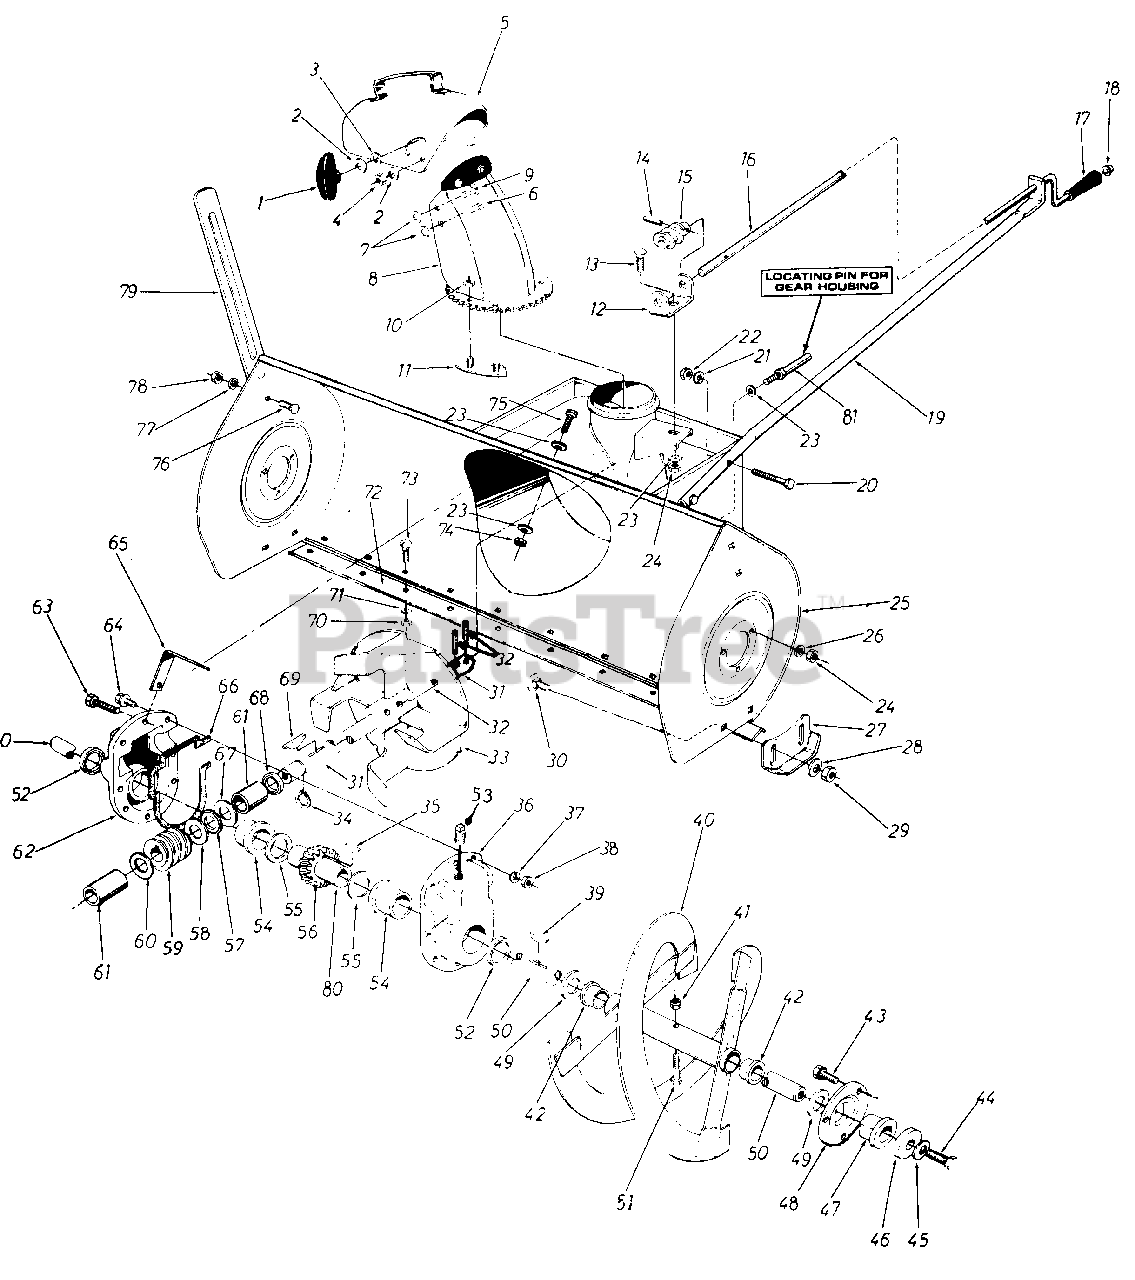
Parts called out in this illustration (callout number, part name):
1	Hand Knob Ass'y.
2	Bell. Wash. .345 I.D. x .88 O.D. x .060
3	Fl.-Wash. .312 I.D. x 1.125 O.D. x .125
4	Hex Cent. L-Nut 5/16-18 Thd.
5	Top Chute Ass'y.
6	Carriage Bolt 5/16-18 x 1.50" Lg.
7	Fl.-Wash. .53 I.D. x 1.25 O.D. x .100
8	Chute Ass'y.
9	Carriage Bolt 5/16-18 x 1.00" Lg.
10	Hex Cent. L-Nut 1/4-20 Thd.
11	Chute Flange Keeper Ass'y.
12	Chute Bracket
13	Carriage Bolt 5/16-18 x .62" Lg.
14	Spring Pin Roll 1/8" Dia. x 1.75 Lg.
15	Worm-R.H. w hree Threads
16	Chute Crank
17	Knob Black 3/8" Dia. Hole
18	Push Nut 3/8" rod.
19	Chute Crank Support Tubing
20	Hex Scr. 3/8-24 x 1.25" Lg.
21	L.-Wash. 3/8" Scr.
22	Hex Ins. Jam L.-Nut 3/8-24 Thd.
23	Bell.-Wash. .345 I.D. x .88 O.D. x .060
24	Hex Nut 5/16-18 Thd.
25	Blower Housing Assembly
26	L-Wash. 5/16" Scr.
27	Slide Shoe
28	Bell. Wash. .400 I.D. x .88 O.D. x .060
29	Hex Nut 3/8-16 Thd.
30	Carriage Bolt 3/8-16 x .75" Lg.
31	Blower Axle
32	SpringPinSpiral5/16" Dia. x 1.75" Lg.
33	Blower Fan Ass'y.
34	Snap Ring for .875" Dia. shaft
35	#91 Woodruff Key 1/4" x 3/4" Dia.
36	Gear Housing Half-L.H.
37	L.-Wash. 5/16" Scr.
38	Hex Ins. L.-Nut 5/16-18 Thd.
39	91 Woodruff Key 1/4" x 3/4" Dia.
41	Hex Ins. L-Nut 5/16-18 Thd
42	Plastic Bushing
43	Hex Sems Scr. 5/16-18 x .75" Lg.
44	Hex Scr. 5/16-18 x .88" Lg. Speco
45	Belleville Wash. .345" I.D. x .88" O.D.
46	Wash. .390 I.D. x 1.75" O.D. x 3/16" Thk.
47	Flange Bearingw/flats 1.00" I.D.
48	Bearing Housing
49	Fl-Wash. 1.00" I.D. x 1.75" O.D. x .100
50	Spiral Axle
51	Hex Scr. 5/16-18 x 1.75" Lg.
52	Oil Seal-1.50" I.D.
53	Sq. Hd. Pipe Plug 3/8" Thd.
54	Flange Bearing 1.503 I.D.
55	Fl.-Wash. 1.50" I.D. x 2.0" O.D. x .030
56	Double Threaded Worm Gear-L.H.
57	Thrust Bearing .88" I.D. x 1 .44" O. D.
58	Fl.-Wash. .88" I.D. x 1.5" O.D. x .030
59	Double Threaded Worm-L.H.
60	Fl-Wash. .88 I.D. x 1.4" O.D. x .155
61	Sleeve
62	Gear Housing Half-R.H.
63	Hex Scr. 5/16-18 x 1.25" Lg.
64	Hex Scr. 5/16-18 x 1.00" Lg.
65	Gear Housing Support Brkt
66	Rubber Gasket
67	Fl.-Wash. .88" I.D. x 1.4" 0 D. x .155
68	Oil Seal. .875" I.D.
69	#9 Hi-Pro Key 3/16" x 3/4" Dia.
70	Hex Nut 5/16-18 Thd.
71	L.-Wash. 5/16" Scr.
73	Carriage Bolt 5/16-18 x .75" Lg.
74	Hex Nut 5/16-18 Thd.
75	Hex Scr. 5/16-18 x .75" Lg.
76	Carriage Bolt 5/16-18 x .62" Lg.
77	L.-Wash. 5/16" Scr.
78	Hex Nut 5/16-18 Thd.
79	Guide Blade
80	Worm Cear Shaft
81	Stud 3/8-16 x 2.75" Lg.
